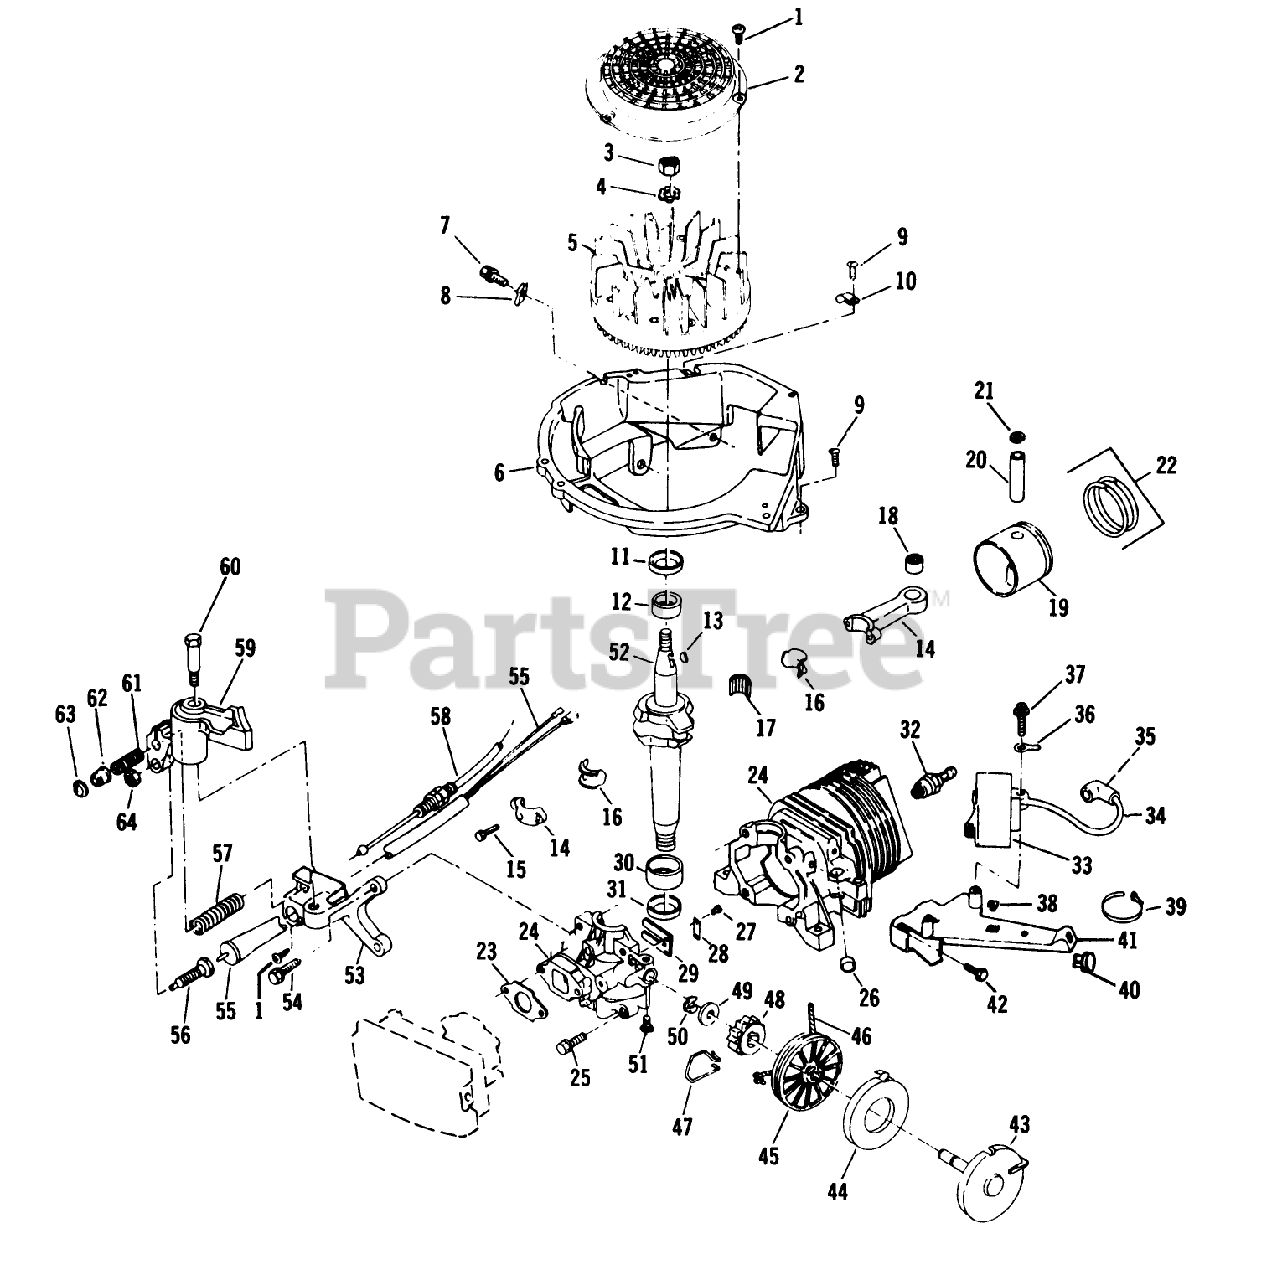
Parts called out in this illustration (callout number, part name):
1	SCREW F
2	SCREEN F'WHEEL S
7	SCREW-SEMS
9	SCREW F
12	BEARING V
15	SCREW-HSH
16	LINER ASM
18	BEARING AY F
21	RING-RETAINING
23	GASKET CARB S
25	SCREW S
26	PLUG-CORE VF
28	PLATE-BACKUP, REED
30	BEARING V
31	SEAL-OIL
34	HT LEAD&COVER XEV
36	TERMINAL S
38	NUT-CLIP
40	NUT-CLIP
45	PULLEY STARTER S
46	ROPE-STARTER
47	SPRING F
49	WASHER S
53	BRACKET-BRAKE F
56	PLUNGER S
57	SPRING-BRAKE
62	ACTUATOR-LEVER, BRAKE
63	RETAINER S
